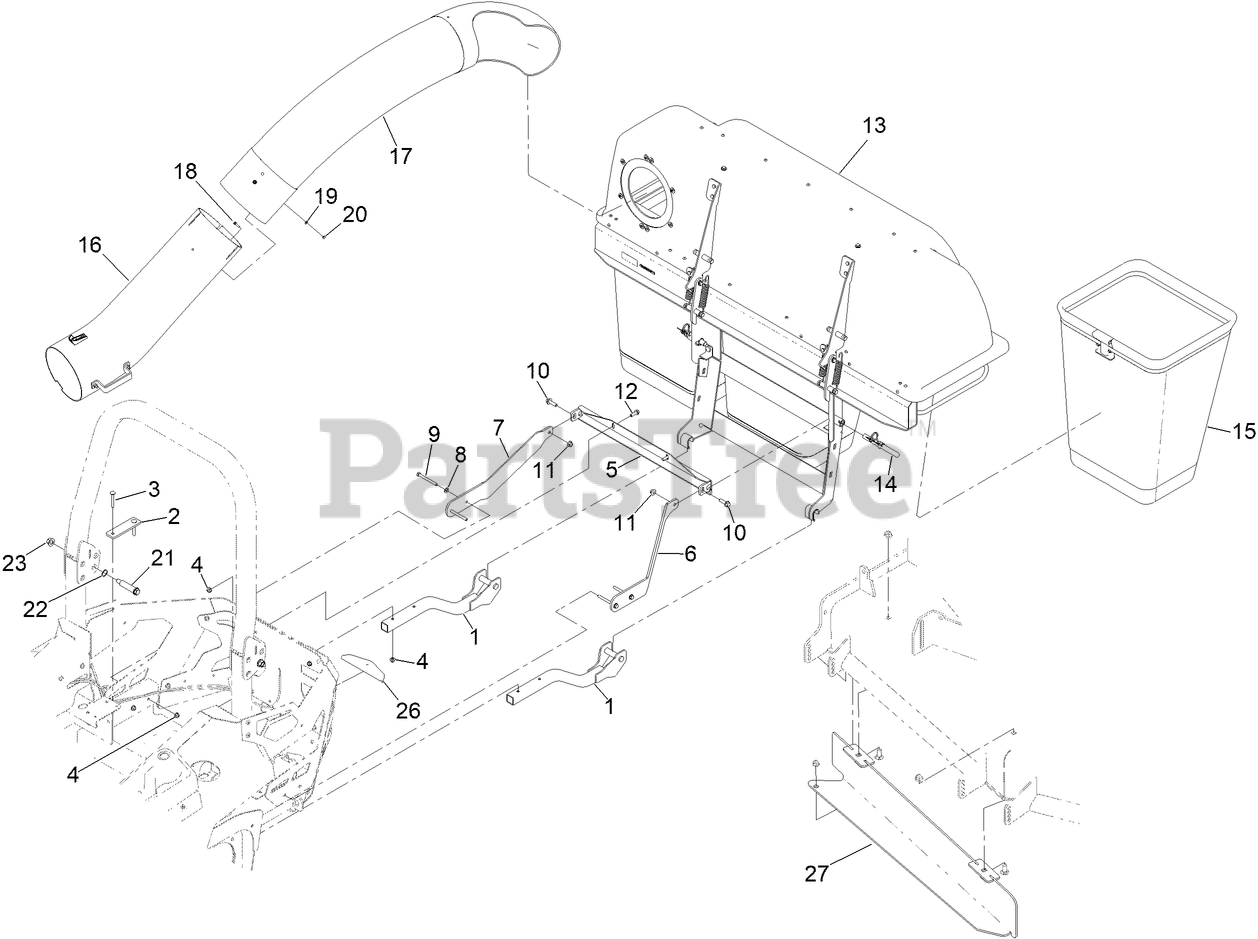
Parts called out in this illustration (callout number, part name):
1	SUPPORT, LOWER [BLACK]
2	PLATE-BACKER
3	BOLT-CARR
4	NUT-HF, NI
5	SUPPORT-BAGGER, UPPER
6	BRACKET-UPPER, LH
7	BRACKET-UPPER, RH
8	WASHER-PLAIN
9	SCREW-HH
10	SCREW-HHF
11	NUT-HF, NI
12	SCREW-HHF
13	TRIPLE BAG HOOD ASM
14	PIN-MOUNT, BAGGER
15	BAG AND FRAME ASM
16	LOWER TUBE ASM
17	TUBE-UPPER
18	SCREW-HWH
19	WASHER-FLAT
20	NUT-LOCK, NI
21	BOLT-SHOULDER
22	WASHER-WAVE
23	NUT-LOCK
26	COVER-HITCH
27	BAFFLE-BAGGER, 60
